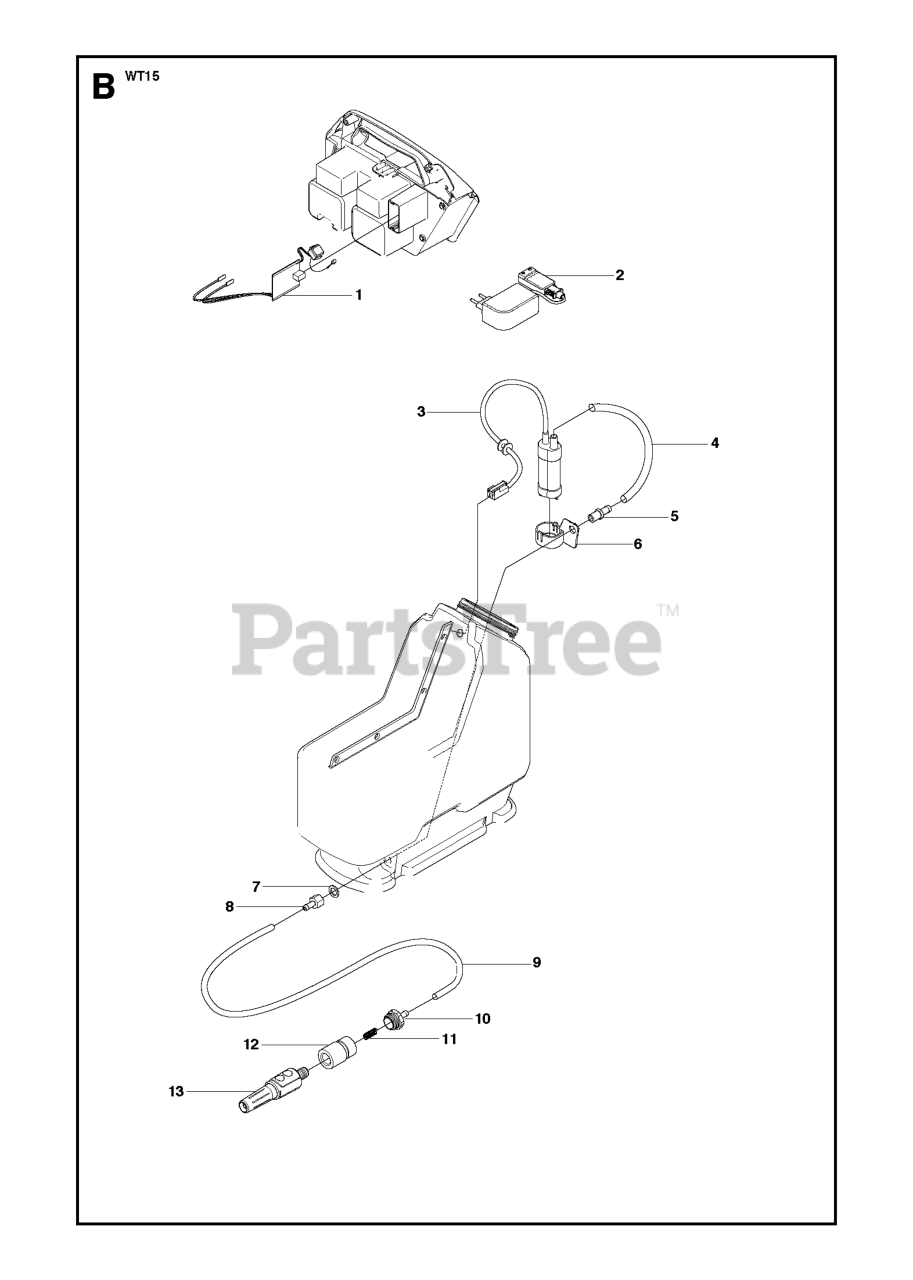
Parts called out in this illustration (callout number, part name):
1	CIRCUIT BOARD ASSY
2	CHARGER
2	SET UP IN ERROR. OKAY TO USE
4	HOSE
9	HOSE
10	HOSE COUPLING
12	FEMALE QUICK COUPLER
13	SPRAY NOZZLE
